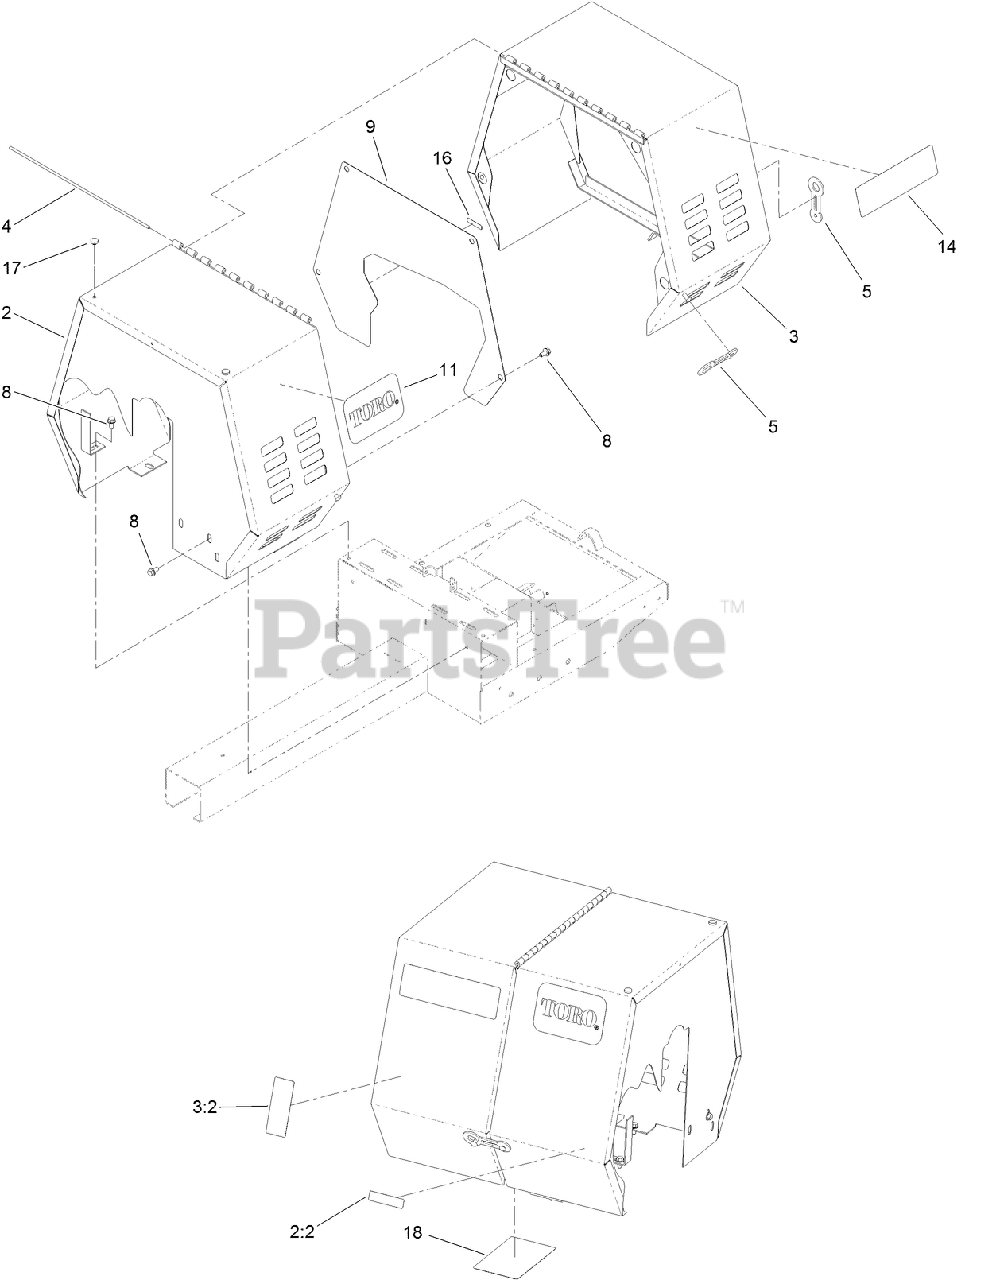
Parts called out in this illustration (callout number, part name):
2	STATIONARY COWL ASM
2:2	DECAL-ARRESTER, SPARK
3	MOVABLE COWL ASM
3:2	DECAL-WARNING
5	LATCH-RUBBER
8	SCREW-HWH
9	PLATE-GUARD, BELT
11	DECAL
16	DECAL-GREASE
17	BUMPER
18	DECAL-SERVICE
